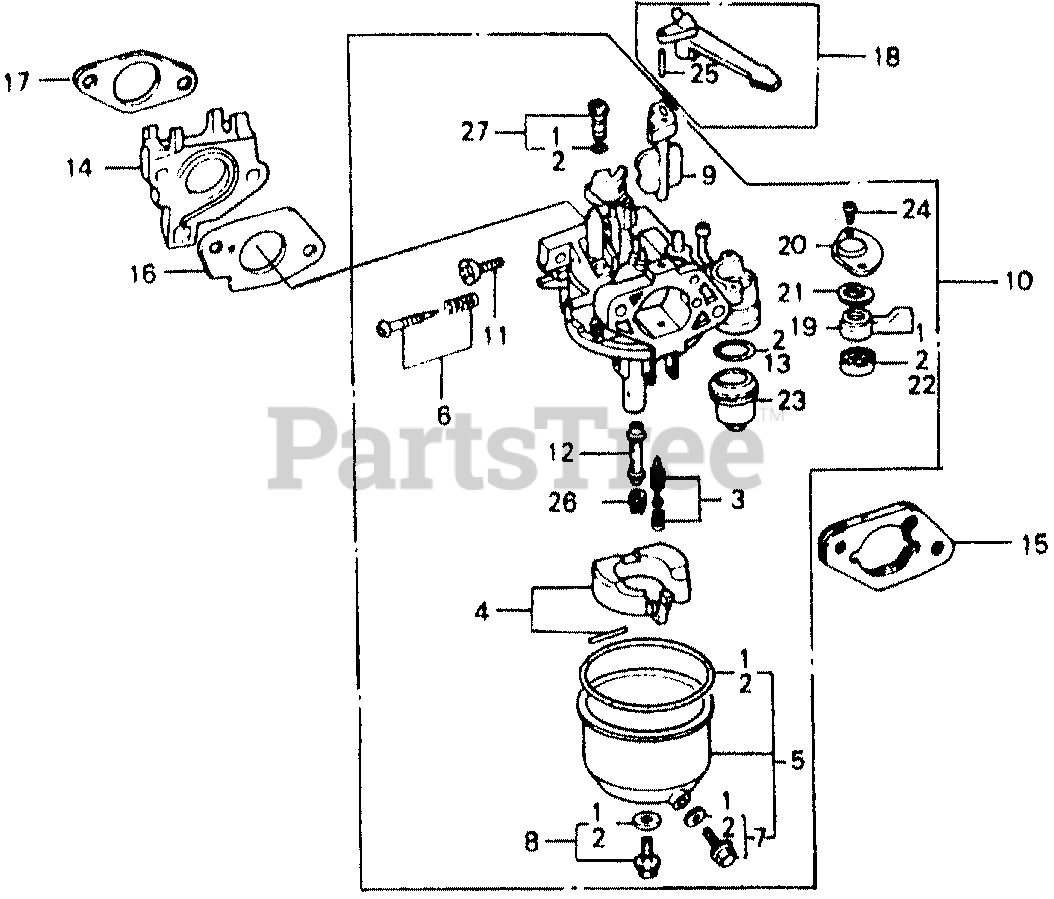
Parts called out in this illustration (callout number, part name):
2	GASKET SET
3	VALVE SET, FLOAT
5	CHAMBER SET, FLOAT
6	SCREW SET, PILOT
8	SCREW SET B
10	CARBURETOR ASSY. (BE15B C)
10	CARBURETOR ASSY. (BE15B E)
11	SCREW, THROTTLE STOP
12	NOZZLE, MAIN
13	GASKET, FUEL STRAINER CUP
14	INSULATOR, CARBURETOR
15	SPACER, CARBURETOR
16	GASKET, CARBURETOR
17	GASKET, INSULATOR
18	LEVER, CHOKE (STD)
19	LEVER, VALVE
20	PLATE, LEVER SETTING
21	SPRING, VALVE LEVER
22	GASKET, VALVE
23	CUP, FUEL STRAINER
24	SCREW, PAN (3X8)
25	PIN, SPRING (2X12)
26	JET, MAIN (#82)
26	JET, MAIN (#85)
26	JET, MAIN (#88)
27	JET SET, PILOT (#38)
